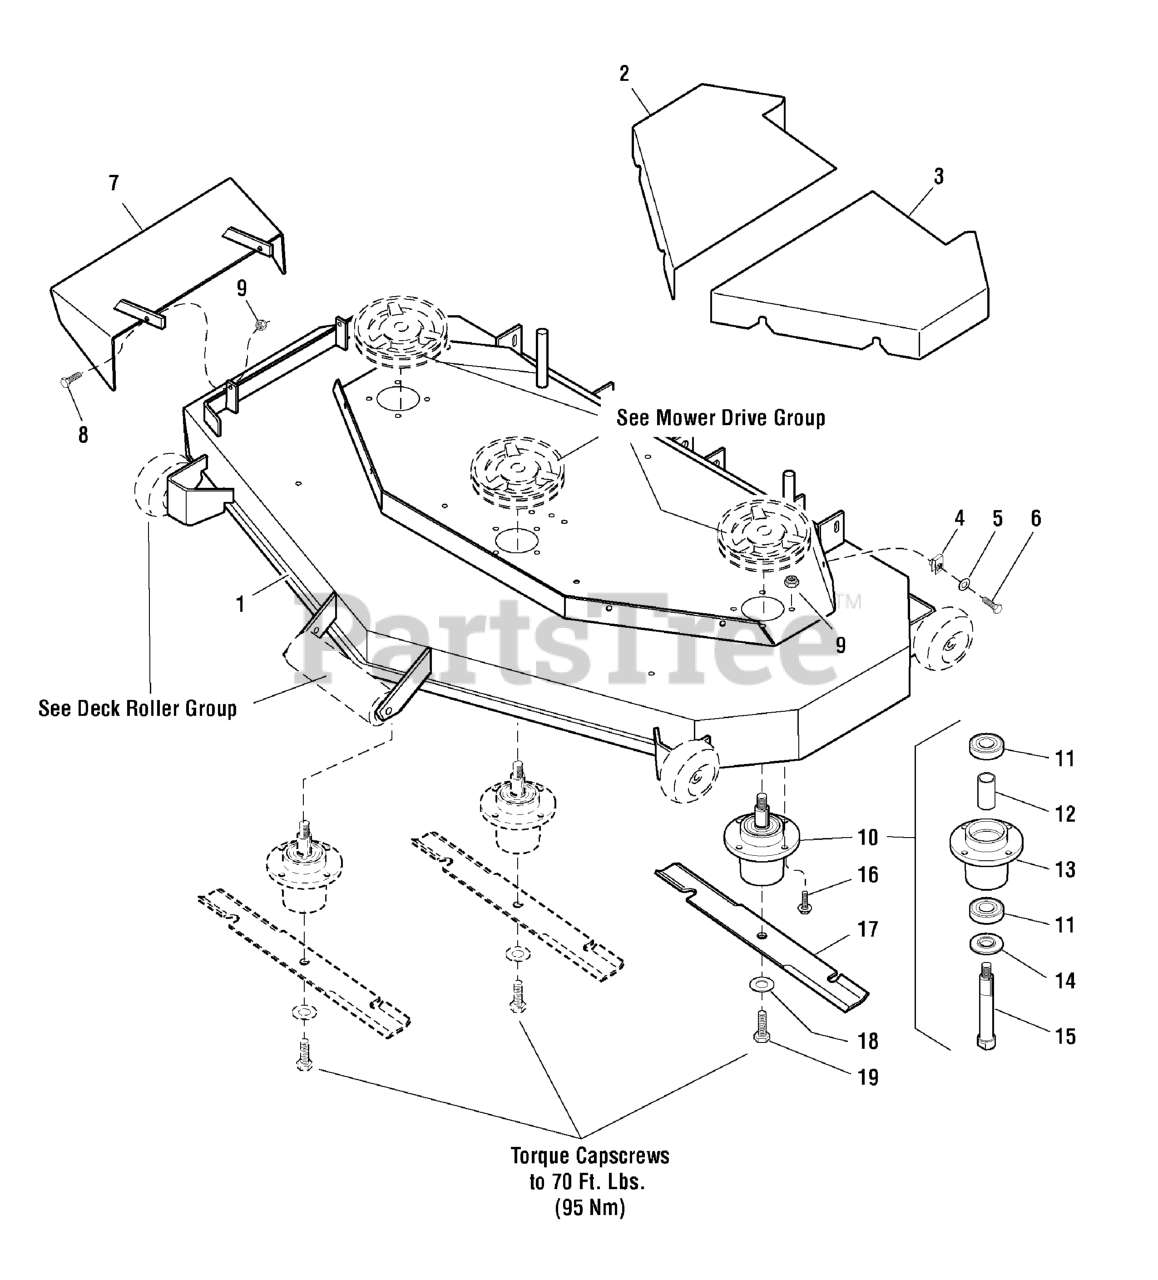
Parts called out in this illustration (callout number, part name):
1	DECK SHELL W/DECALS, 61"
2	SPINDLE COVER-RH
3	SPINDLE COVER-LH
4	BODY CLIP, 5/16-18-7GA MATERIAL
5	WASHER, 5/16" SAE
6	BOLT, 5/16-18 X 3/4 GD5
7	DISCHARGE CHUTE
8	BOLT, 5/16-18 X 1 GD5 YZ
9	NUT, 5/16-18 Hex Nylon Lock
10	* SPINDLE ASSEMBLY, Complete
16	BOLT, Flange Head, 5/16-18 x 1-1/4
17	MOWER BLADE, 21"
18	WASHER, 5/8" USS
19	BOLT, 5/8-11 X 1-3/4 GD8
